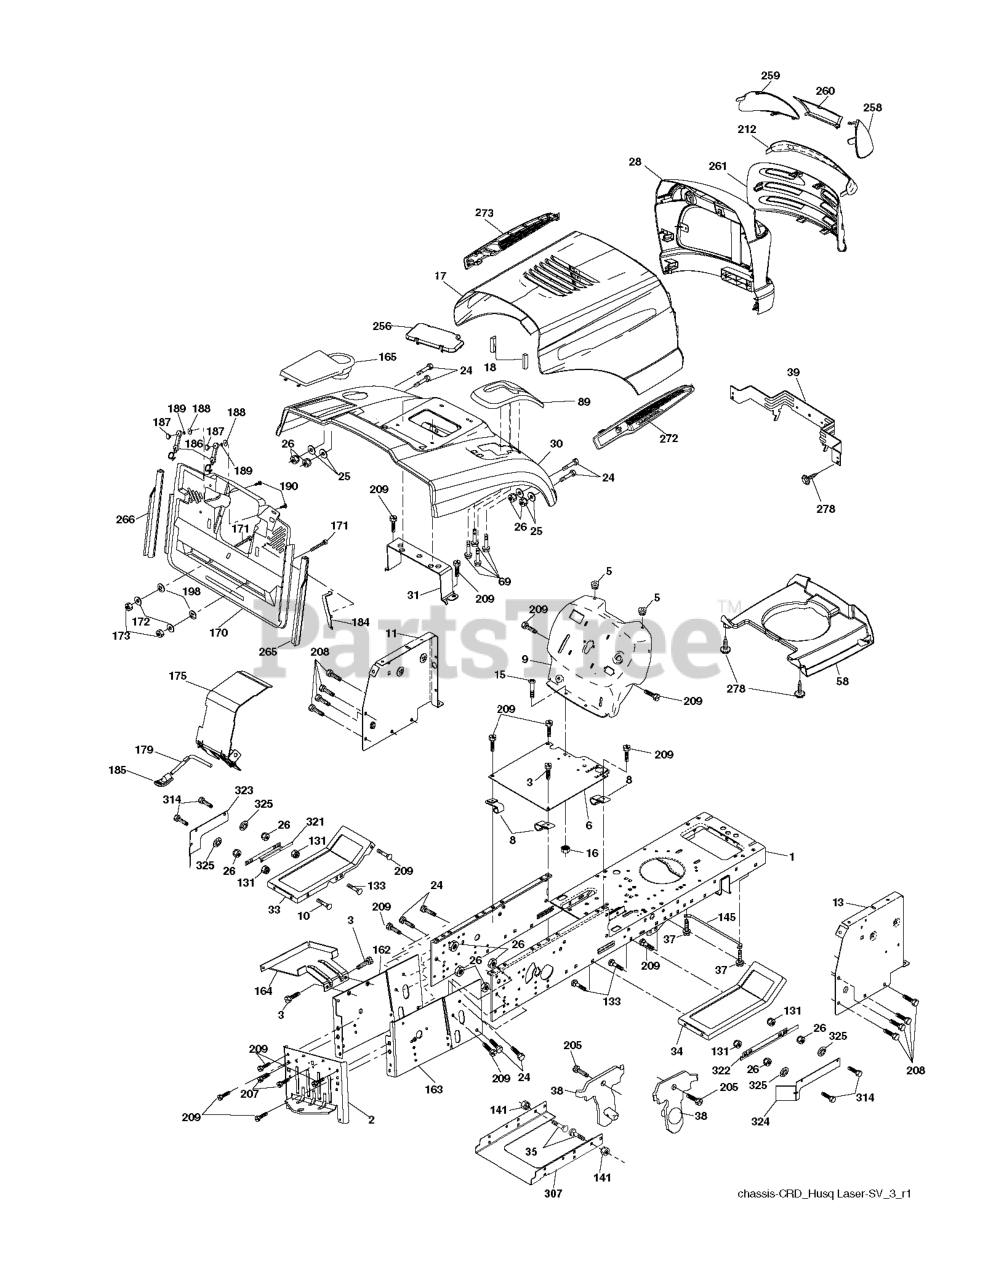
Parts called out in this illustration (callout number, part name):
2	DRAWBAR
3	SCREW 3/8-16X3/4
5	BUMPER.RUBBER.HOOD
6	PLATE
8	CLIP,INSULATOR
9	DASH.SLKSCR.PLM
10	BOLT.3/8-14X1.25
11	PANEL.DASH.LH.LTX
13	PANEL ASM, DASH RH
16	NUT
17	HOOD.PNT.LASER.SV.LT.668
18	BUMPER.HOOD.LARGE.1.75"
24	BOLT
25	WASHER
26	NUT
28	GRILLE.HUSQ.LASER.LT.668
30	FENDER.PNT.CRD.MS-668
31	BRACKET SUPPORT FENDER
33	FOOTREST.PNT.LH.GREY
34	FOOTREST.PNT.RH.GREY
35	BOLT
37	SCREW LT
38	BRACKET ASM PIVOT MOWER REAR
39	BRACKET PIVOT
69	SCREW.HI-LO.CONSOLE
89	CONSOLE.CRD.AUTO.GRY
131	NUT.HEX.3/8-16UNC
133	BOLT D
141	NUT LOCK FLG 3/8-16 UNC
145	ROD.PIVOT.HOOD
162	BRACKET
163	BRACKET EXTEN CHASSIS RH CRD
165	COVER.BATTERY.CRD.BLACK
171	BOLT
172	WASHER
175	DOOR TRAP
179	ROD PIVOT FBI
184	BRACKET.ACTUATOR.BAGGER.SRD
185	KNOB.BRAKE.PARKING.ROD
186	LATCH ASSY
187	WELDNUT
189	LOCKWASHER #10
190	SCREW
205	SCREW LT
207	SCREW, 5/16-18 X 1/2
208	SCREW 3/8-16X1/2
209	SCREW, 3/8-16X3/4
212	INSERT.LENS.REFLECTIVE
256	COVER FENDER CRD
258	LENS LH
259	LENS LH
260	COVER.LENS.HUSQ.LASER.LT.498
261	INSERT.GRILLE.HUSQLASER.LT.498
265	SEALING
266	SEALING
272	VENT.HOOD.LASER.III.SD.RH
278	SCREW.#10 X 0.750.BOS
307	GUARD 107 CRD FRENCH GUARD HYD
314	SCREW 1/4X20
321	SHIELD INNER LEFT
322	SHIELD INNER RIGHT
323	PLATE LEFT
324	PLATE RIGHT
325	PALNUT 1/4
